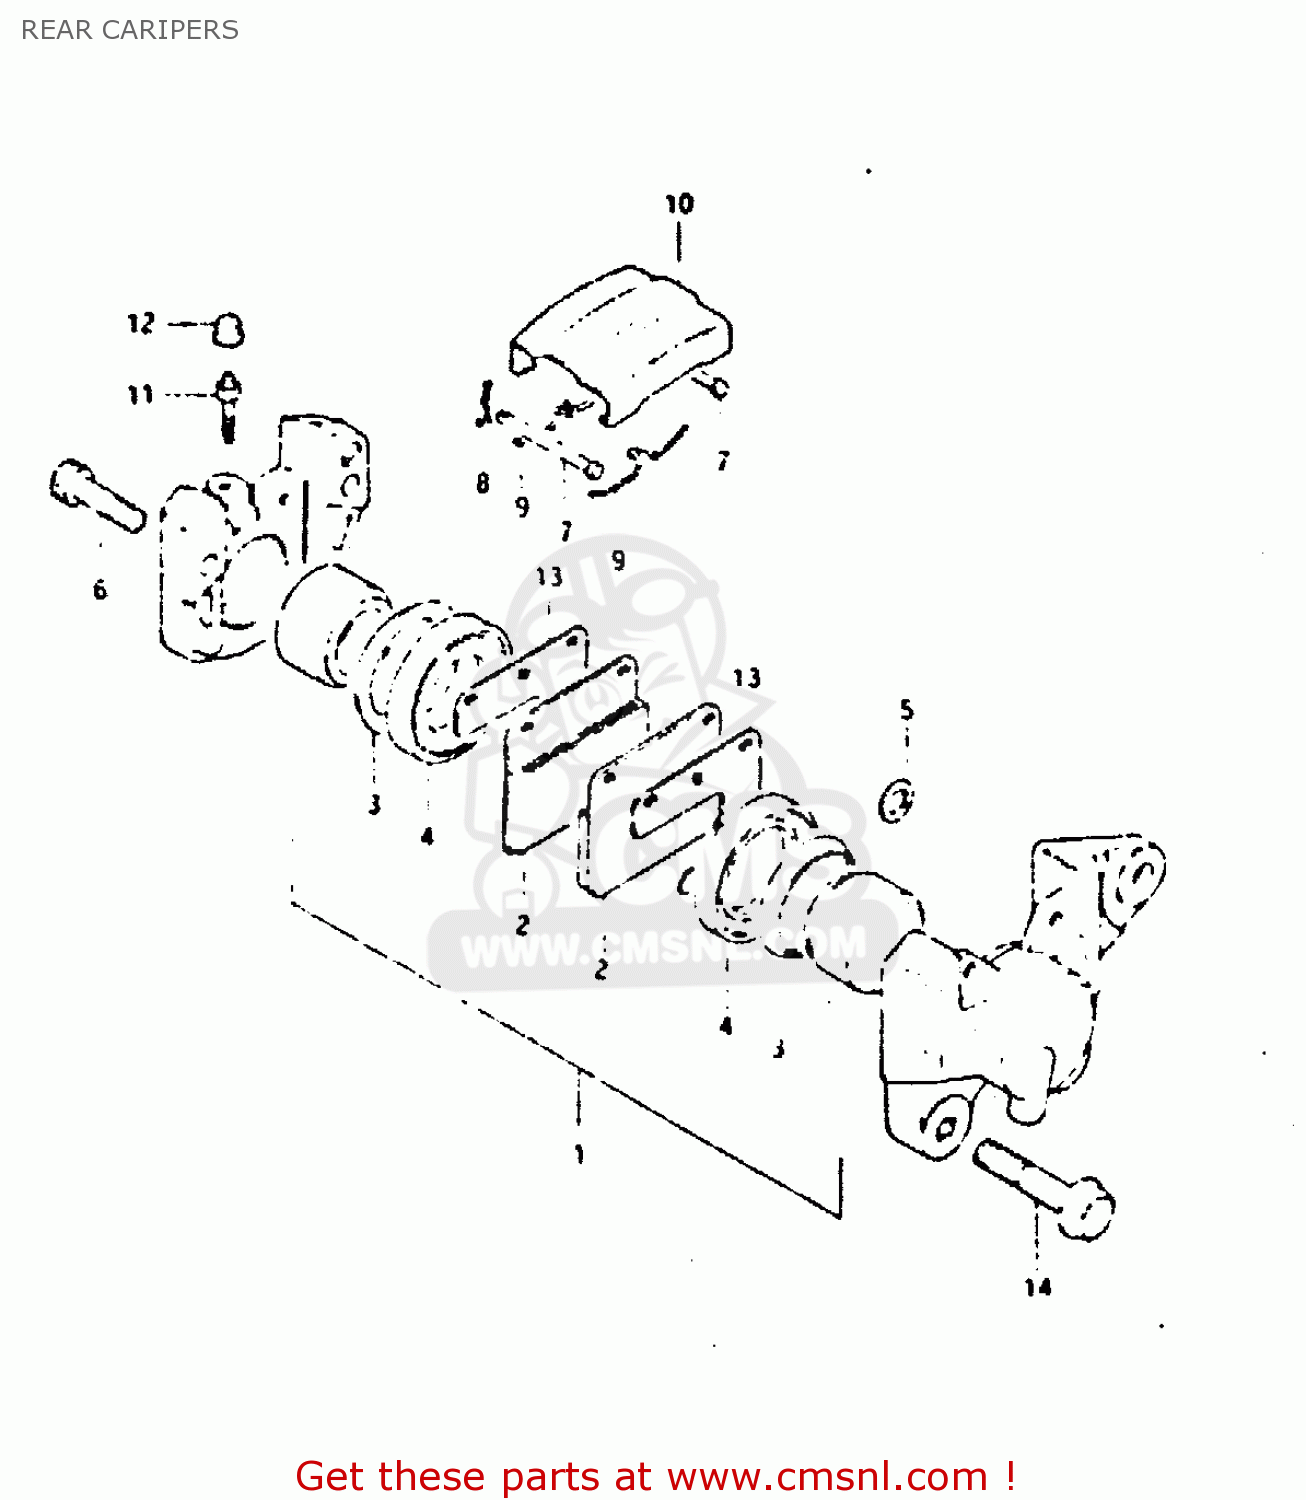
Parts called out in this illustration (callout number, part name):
1	PISTON SET
2	PAD,BRAKE (MCA)
3	SEAL,PISTON
4	BOOT,PISTON
5	SEAL,JOINT
6	BOLT,CALIPER HOUSING
7	PIN,PAD
8	CLIP,PAD PIN
9	SPRING
10	COVER,DUST
11	BLEEDER
12	CAP,BREATHER
13	SHIM,RR CALIPER
14	BOLT
